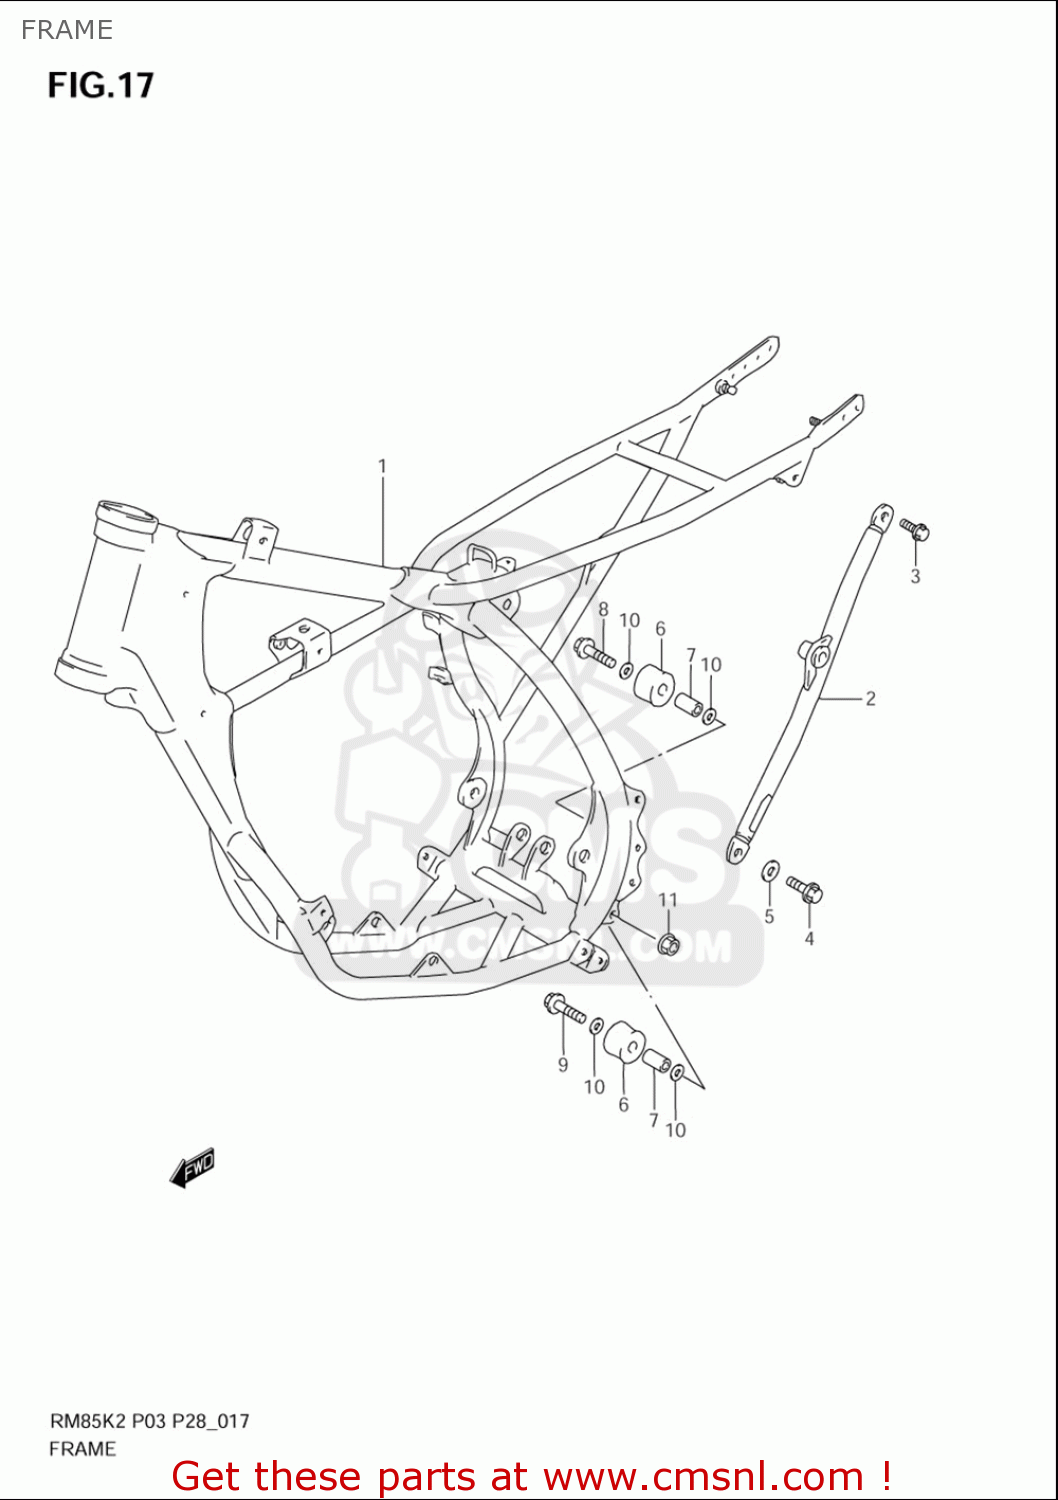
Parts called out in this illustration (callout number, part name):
1	FRAME COMP
2	TUBE,FRAME SIDE,L(GRAY)
3	BOLT(8X22)
4	BOLT(8X16)
5	WASHER
6	ROLLER,CHAIN CONTROL
7	SPACER(8.6X12.2X25.5)
8	BOLT(8X38)
9	BOLT
10	SHIM(8X16X1)
11	NUT
